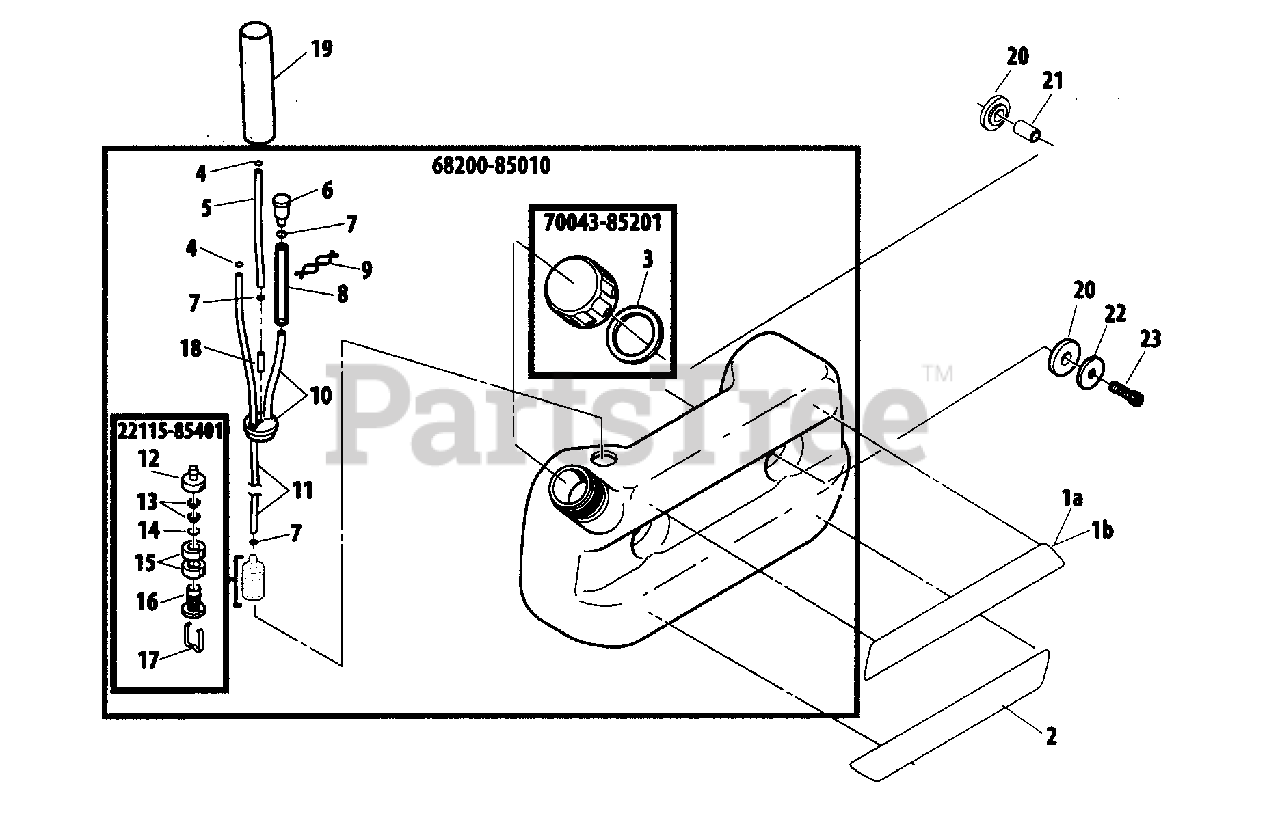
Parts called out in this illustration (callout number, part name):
1A	LABEL - MODEL EB480
1B	LABEL - MODEL EB500
2	LABEL
3	GASKET, CAP
4	CLIP
5	TUBE
6	VENT, FUEL TANK
7	RING, RETAINING - 6
8	TUBE
9	CLIP
10	PIPE ASSY
11	TUBE
12	WEIGHT, FUEL FILTER
13	SCREEN, FILTER
14	RING, RETAINING
15	FILTER, FUEL
16	CASE, FILTER
17	CLIP, FILTER
18	CONNECTOR, PIPE
19	TUBE
20	CUSHION
21	BUSHING
22	COLLAR
23	SCREW - 6X25
22115-85401	FILTER, FUEL
68200-85010	FUEL TANK ASSY
70043-85201	CAP ASSY
